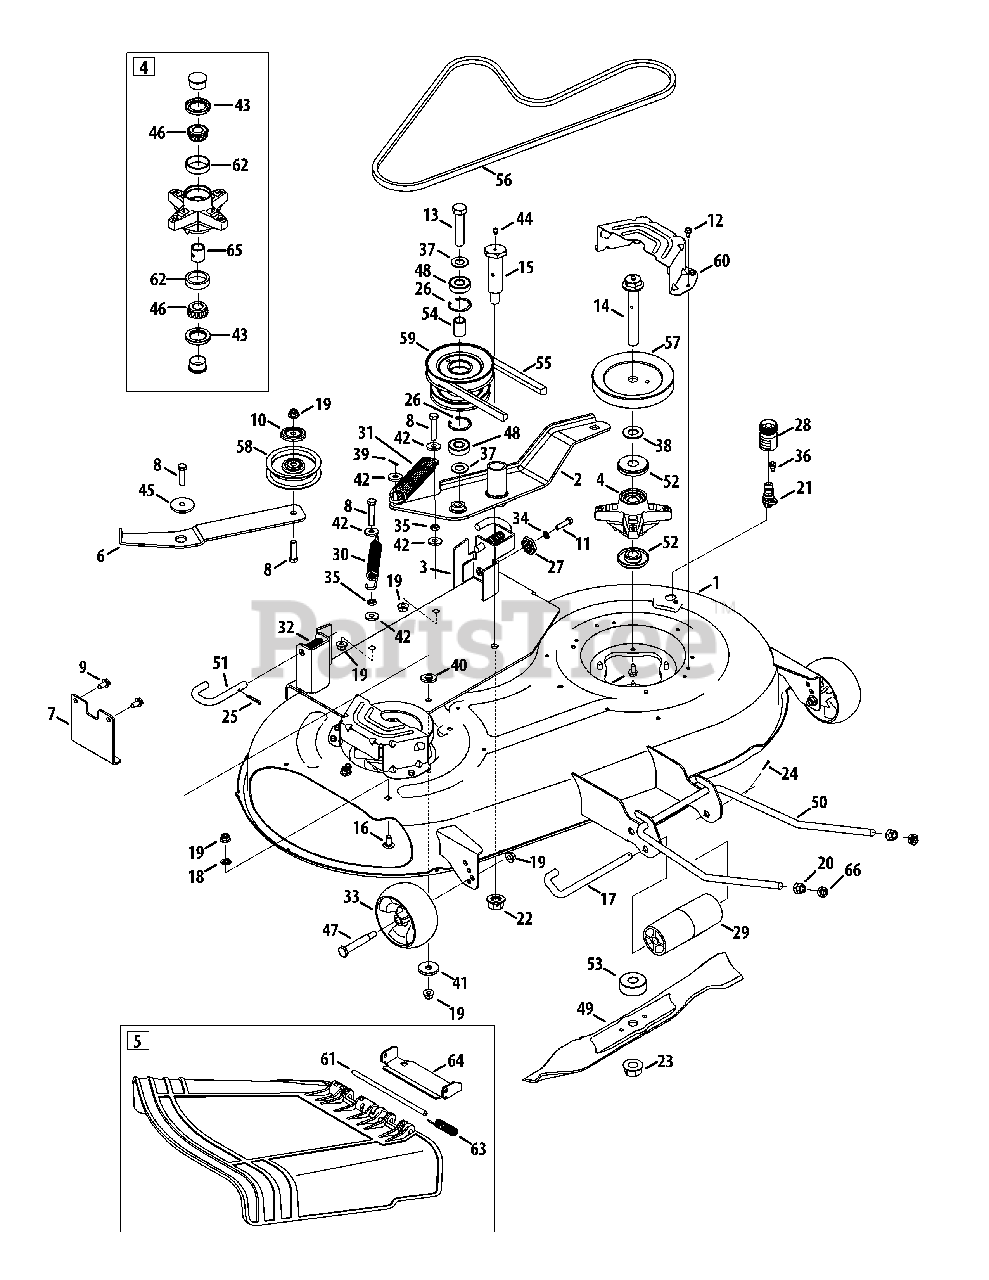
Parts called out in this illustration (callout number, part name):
3	Hanger Adjustment Bracket
4	Spindle Assembly
5	Chute Ass’y, Deflector 42" Offset
6	Idler Bracket
7	Up-Stop Front Bracket
8	Hex Screw, 3/8 x 16 x 1.75
9	Hex Washer Screw, 5/16-18 x .750
10	Pulley Cap
11	Hex Screw, 5/16-18 x 1.25
12	Hex Washer Screw, 1/4-20 x .500
13	Hex Screw, 5/8-18 x 3.00
14	Spindle Bolt, 3/4-16 x 5.37
15	Shoulder Screw, 1.0 x 3.00
16	Carriage Bolt, 3/8-16 x 1.00
17	Roller Pin, 1/2 x 7.31
18	Push Nut, 3/8
19	Flange Lock Nut, 3/8-16
20	Hex Nut, 1/2-13
21	Deck Wash Nozzle
22	Flange Lock Nut, 5/8-18
23	Flange Lock Nut, 3/4-16
24	Cotter Pin, 3/32 x 1.25
25	Cotter Pin, 5/32 x 1.25
26	Retainer Ring
27	Deck Adjustment Gear
28	Water Nozzle Adapter
29	Front Roller
30	Extension Spring, .850 x 6.415
31	Extension Spring, 1.25 x 6.9
32	Compression Spring, .66 x 1.8
33	Deck Wheel, 5.0
34	Lock Washer, 5/16
35	Jam Nut, 3/8-16
36	Shoulder Screw, 1/4-20 x 0.50
37	Flat Washer, .65 x 1.25 x .075
38	Flat Washer, .760 x 1.50 x .120
39	Cotter Pin, 3/32 x .75
40	Flat Washer, .385 x 1.0 x .030
41	Flat Washer, .45 x 1.5 x .172
42	Flat Washer, .385 x 1.00 x .135
44	Drive Lube Fitting, 3/16
45	Shoulder Spacer, .8840 x .190
46	Cone Bearing, .750
47	Shoulder Screw, 1/2 x 2.50
48	Ball Bearing, .625 x 40 x 12
49	2-in-1 Blade, 21.23
50	Front Lift Rod
51	Mower Support Pin
52	Deck Spindle Spacer
53	Spacer, .760 x 2.000 x .790
54	Spacer, .88 x .635 x 1.25
58	Idler Pulley
59	Double Pulley
60	Belt Cover
62	Bearing Cup, .750
63	Torsion Spring, .44 x 2.0
64	Chute Bracket
65	Bearing Spacer, .78 x 1.0 x 1.0425
66	Nut, Jam, 1/2-13
